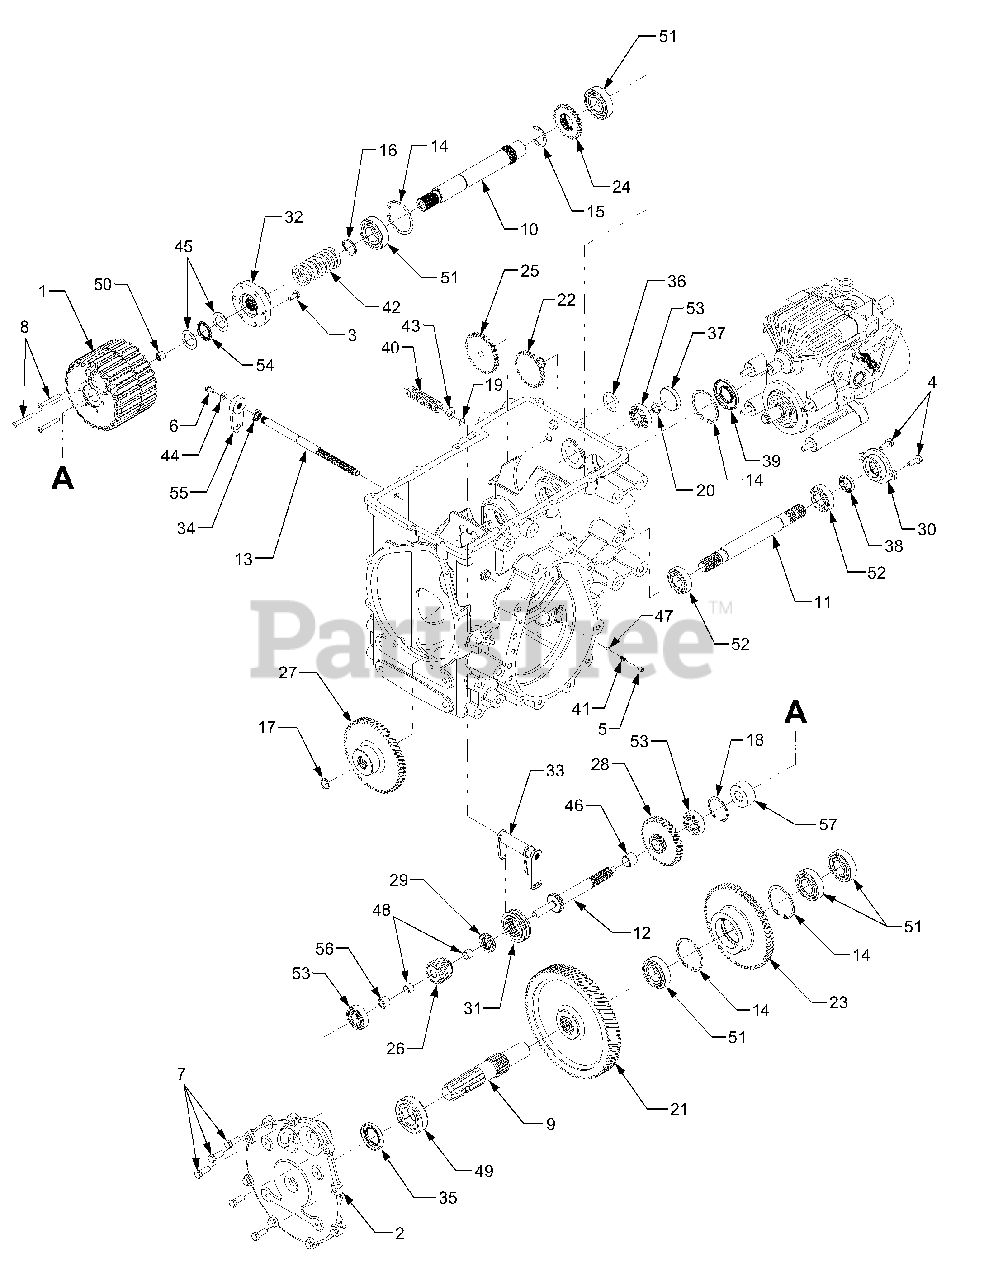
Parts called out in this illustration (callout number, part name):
1	Clutch Assembly, PTO
2	Housing, Rear
3	Screw, Hex Cap Lock, 1/4-20 x .62
4	Screw, Hex Wash Hd, 5/16-18 x .875 GR5
5	Screw, Cup Set, 5/16-18 x 3/8
6	Screw, Hex Cap, 1/4-20 x .5 GR5
7	Screw, Hex Cap Lock, 3/8-16 x 1.0 GR5
8	Screw, Round Hd, 6mm x 40mm
9	Shaft, 540 PTO
10	Shaft, Input
11	Shaft, 2000 PTO
12	Shaft, PTO Back
13	Shaft, PTO Actuator
14	Ring, Retaining
15	Ring, Retaining
16	Ring, Retaining
17	Ring, Retaining
18	Ring, Retaining
19	Ring, Retaining
20	Ring, Retaining
21	Gear, 540 PTO: 81T
22	Gear, Auxiliary Drive Idler: 28T
23	Gear, 2000 PTO: 61T
24	Gear, Auxiliary Drive Pinion: 28T
25	Gear, Auxiliary Drive: 32T
26	Gear, 540 PTO Pinion: 14T
27	Gear, 2000 PTO Pinion: 54T
28	Gear, 2000 PTO Pinion: 34T
29	Gear, Spline Coupling
30	Cover, 2000 PTO
31	Collar, 2 Speed
32	Coupling, PTO
33	Actuator, PTO
34	Seal, Oil
35	Seal, Oil
37	Plug, Oil
38	Seal, Oil
39	Seal, Oil
40	Spring, Compression
41	Spring, Detent
42	Spring, Compression
43	Washer, Flat, .56 x 1.0 x .040
44	Washer, Flat, .25 x .630 x .0515
45	Washer, Thrust, 1.007 x 1.542 x .03
46	Bearing, Sleeve, 20mm x 23mm x 20mm
47	Ball, Detent
48	Bearing, Sleeve, 13mm x 15mm x 10mm
49	Bearing, Ball
50	Bearing, Needle
51	Bearing, Ball
52	Bearing, Ball
53	Bearing, Ball
54	Bearing, Needle Thrust
55	Arm, PTO Select
56	Spacer, 13mm x 20mm x 14mm
57	Spacer, .80 x 1.85 x .855
